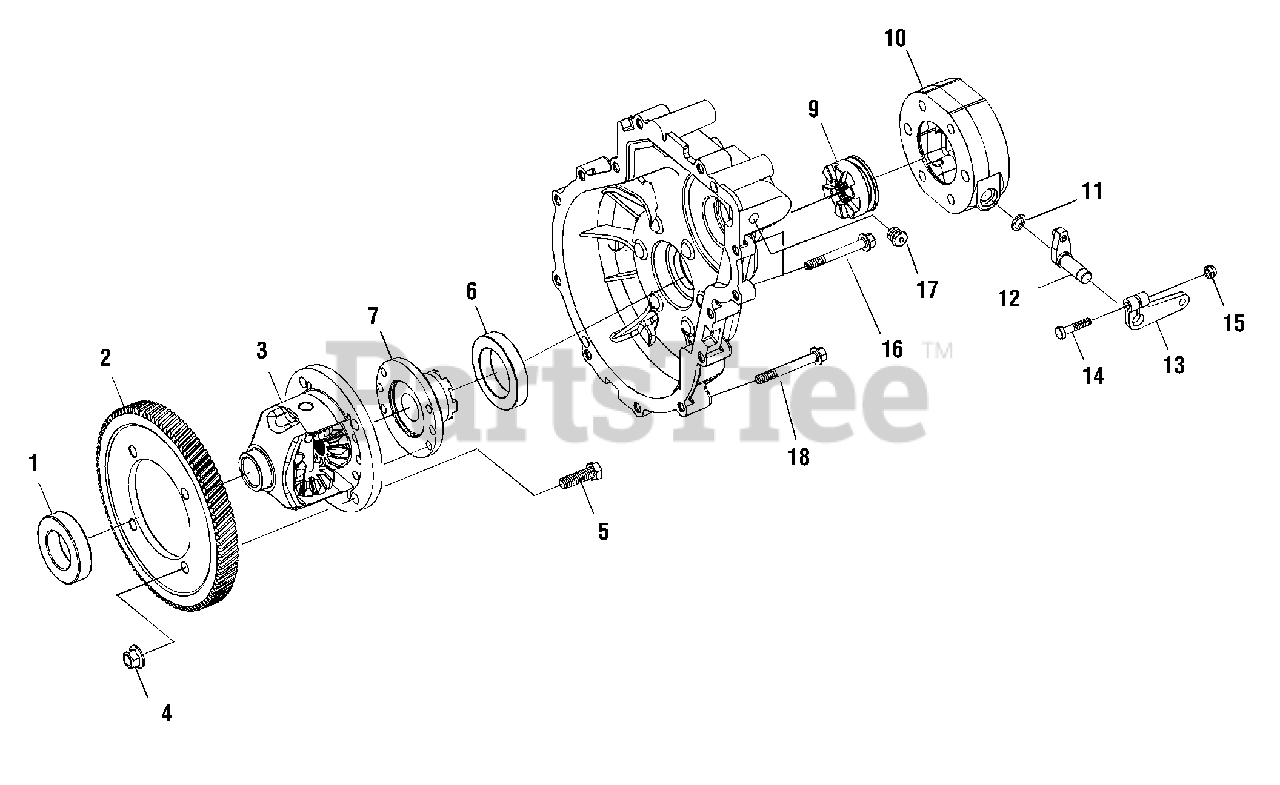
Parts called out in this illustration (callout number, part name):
1	Bearing, Ball
2	Gear, Helical (Ring)
3	Assembly, Differential
6	Bearing, Ball
7	Flange, Half, Differential
8	Screw, Socket Head
9	Gear, Clutch Differential Lock
10	Housing, Differential Lock
12	Assembly, Shift Shaft
13	Lever, Actuating
14	Screw, Hex Head
16	Screw, Flange Head
18	Screw, Flange Head
